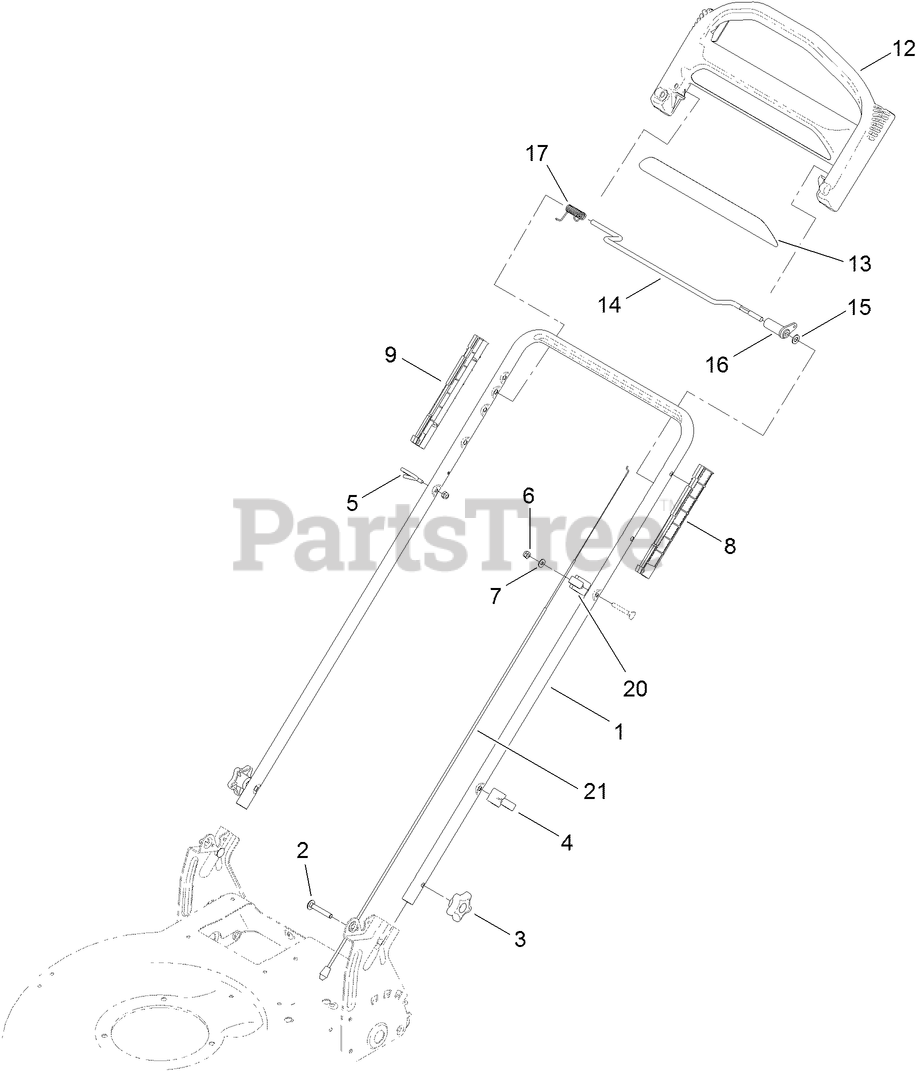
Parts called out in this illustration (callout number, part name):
2	BOLT-CARR
3	KNOB-HANDLE
4	GUIDE-CABLE
5	GUIDE-ROPE
6	NUT-LOCK, NI
7	WASHER-FLAT
8	GUIDE-LH
9	GUIDE-RH
12	HANDLE-CONTROL
13	DECAL-HANDLE
15	WASHER-PLAIN
16	LEVER-TRACTION
21	CABLE-TRACTION
